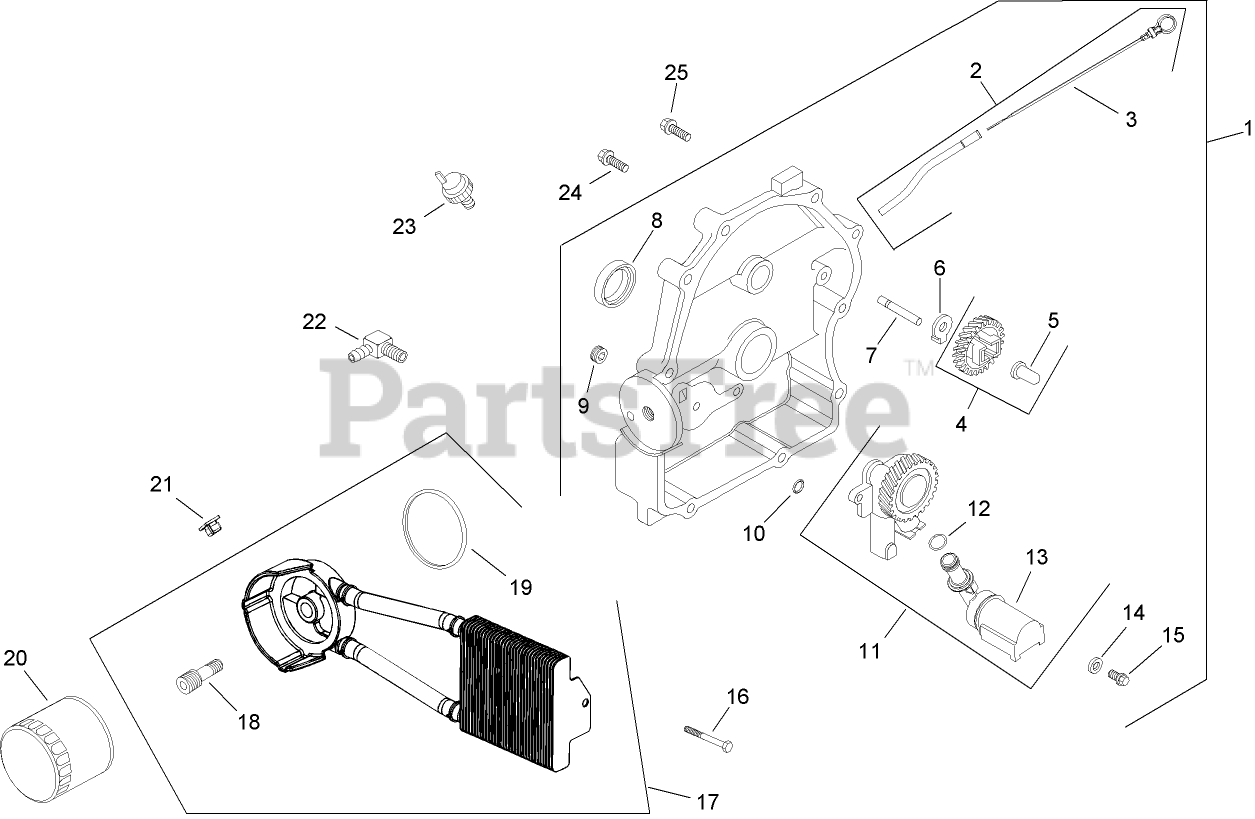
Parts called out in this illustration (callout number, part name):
1	Closure Plate ASM
2	DIPSTICK AND DIPSTICK TUBE ASM
3	Dipstick
4	GOVERNOR GEAR W/PIN KIT
5	PIN-REGULATING, GOVERNOR
6	TAB-LOCKING
7	SHAFT-GEAR, GOVERNOR
8	SEAL-OIL (P-T-O END)
9	PLUG-PIPE, COUNTERSUNK (1/8)
10	O-Ring
11	OIL PUMP ASM
12	O-RING
13	TUBE-PICK UP, OIL
14	WASHER-FLAT (6 MM)
15	SCREW-FLANGE, THREAD FORMING (M6X1.0X25)
16	SCREW-TAPPING
17	OIL COOLER KIT (METAL)
18	NIPPLE-FILTER, OIL
19	O-RING
20	FILTER-OIL
21	Nut-Plastic
22	Connector-Hose, 90 Deg
23	SWITCH-PRESSURE, OIL
24	Screw-HF (M8x1.25x45)
25	SCREW-FLANGE (M8X1.25X45)
